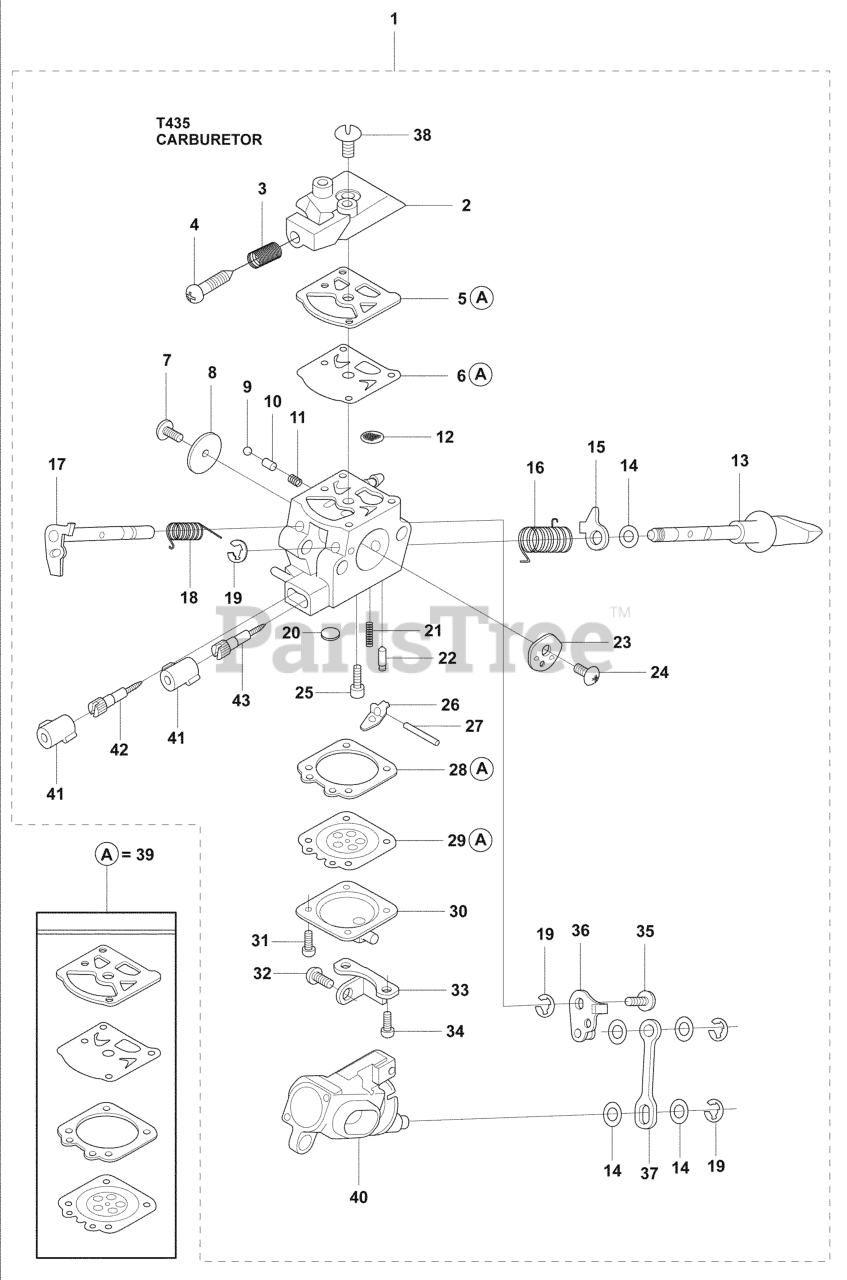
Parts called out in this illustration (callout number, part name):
1	CARBURETOR WT 942
9	BALL
10	PISTON
12	SCREEN
17	SHAFT ASST THRO
18	SPRING RETURN
19	RING, E
22	VALVE INLET
23	CHOKE VALVE
29	DIAPHRAGM
31	SCREW ASSY
34	SCREW ASSY
36	LINK ASSY THROT
39	RP GASKET KIT
40	BODY ASSY AIR V
